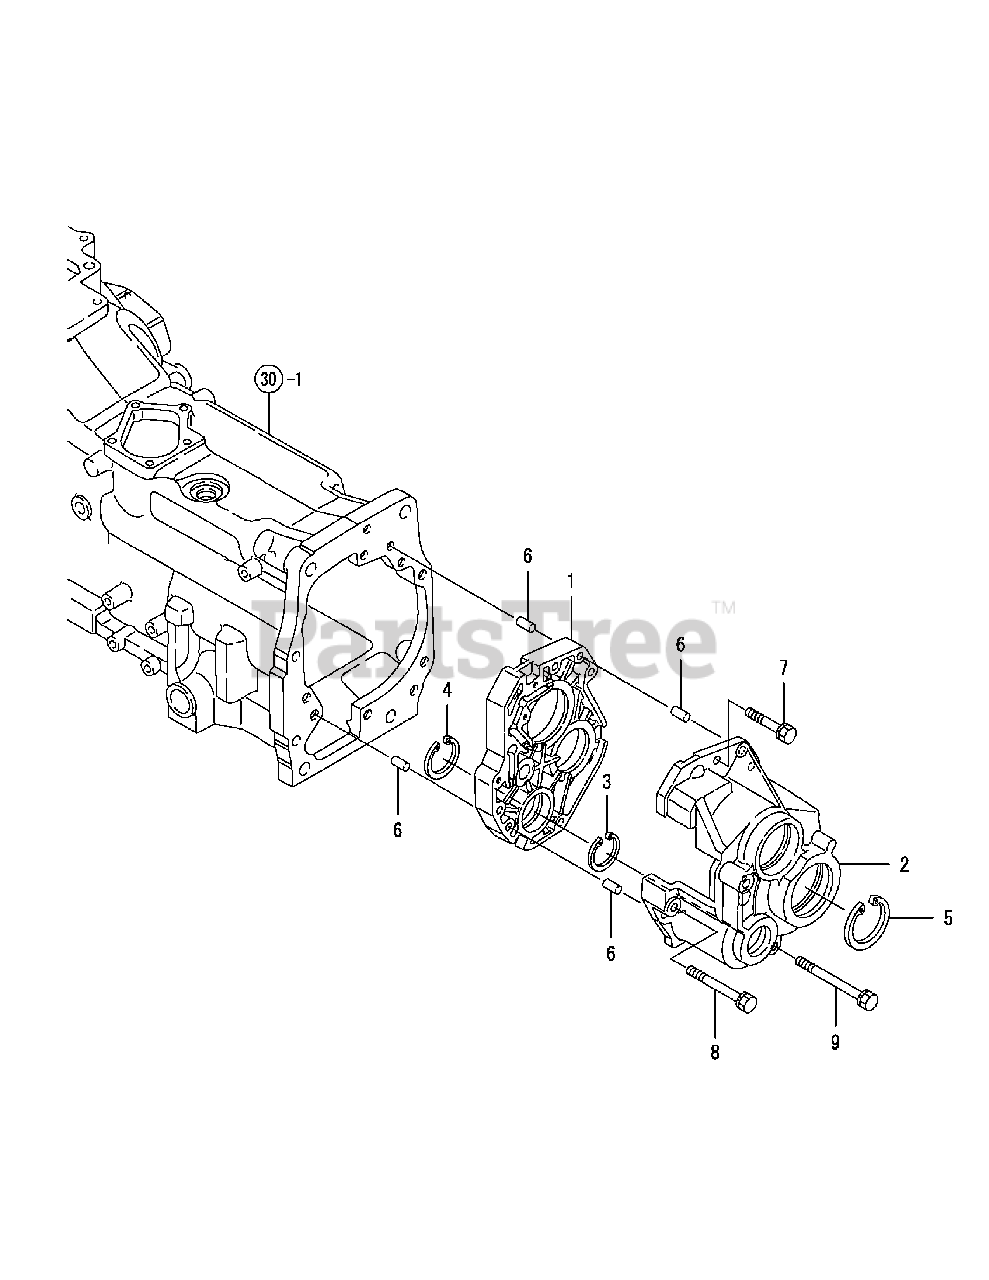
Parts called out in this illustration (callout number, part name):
6	PARALLEL PIN 10X20
8	BOLT W/WASHER 10X 85
9	BOLT,SPRING 10X150
